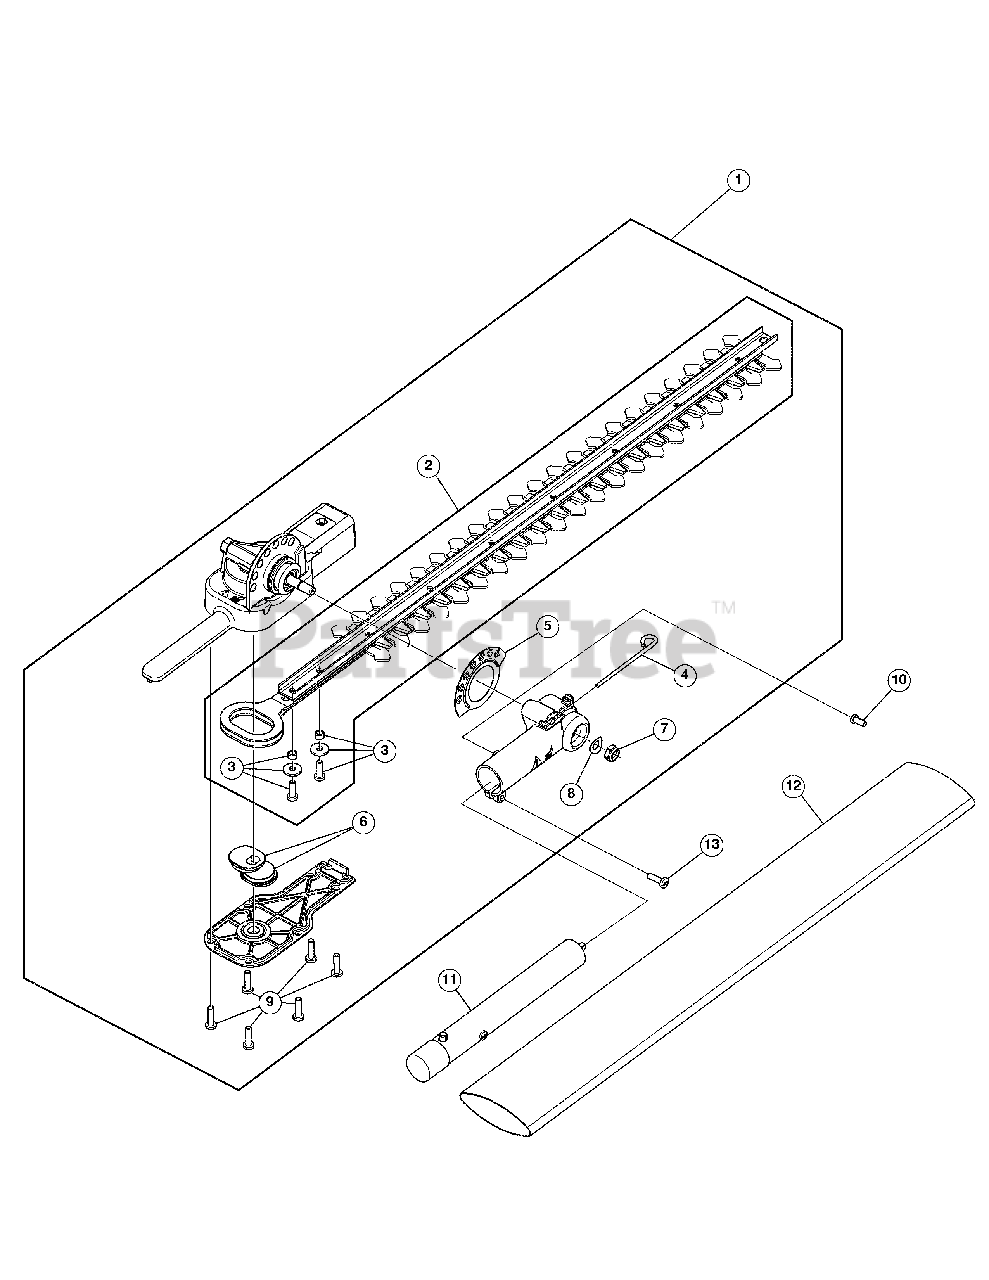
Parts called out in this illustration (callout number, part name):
1	Gearbox (includes 2 - 9)
2	Blade Assembly (includes 3)
3	Blade hardware
4	Locking Lever
8	Wavy Washer
10	Anti-Rotation Screw
11	Boom Assembly
12	Blade Guard
13	Screw
